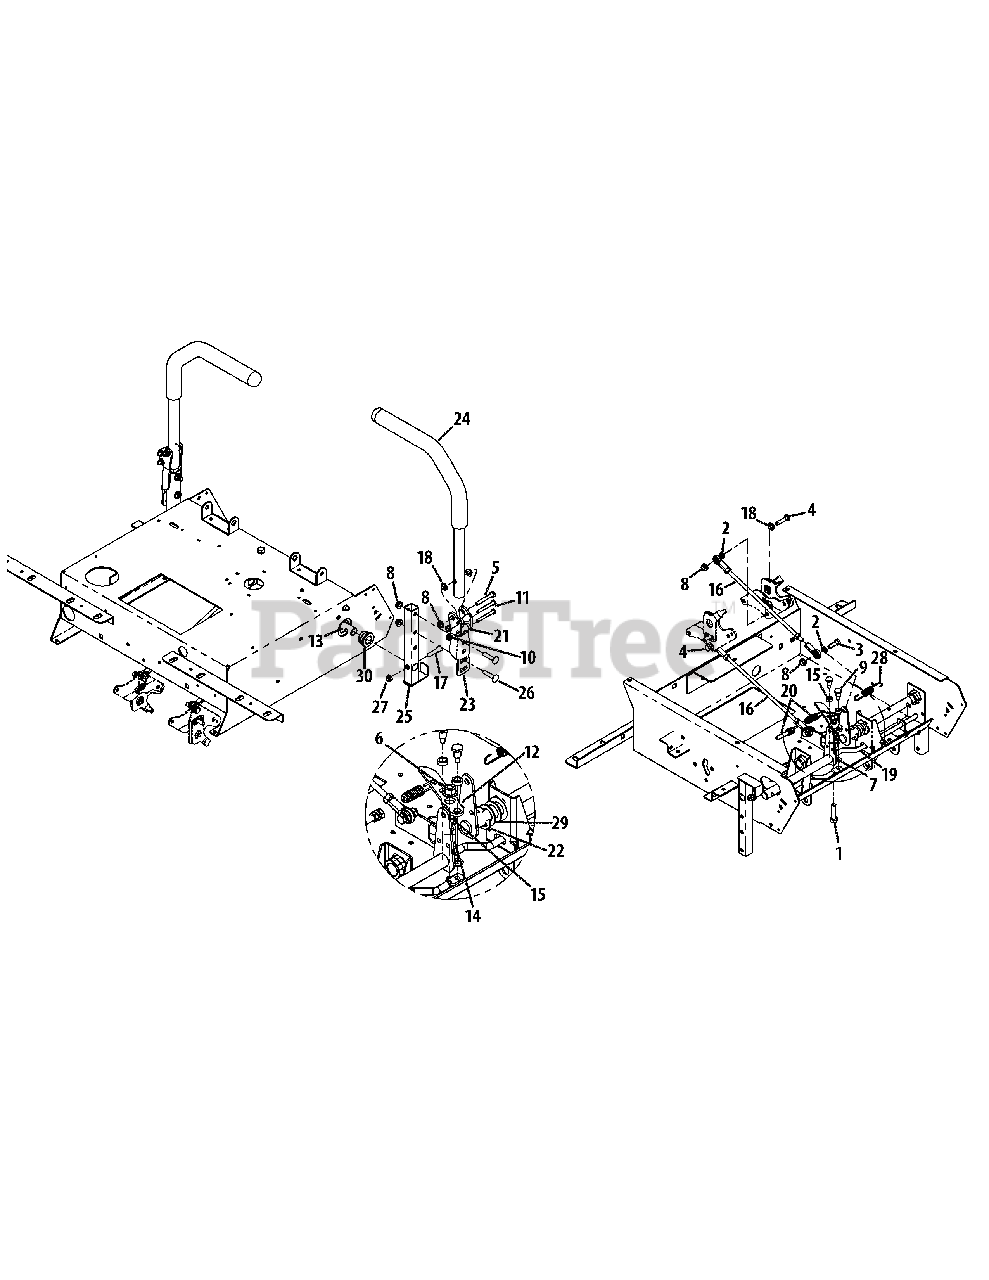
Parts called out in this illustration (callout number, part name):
1	Hex Cap Screw, 3/8-16 x 1-1/2
2	Flat Washer, 5/16
3	Hex Head Cap Screw, 5/16-18 x 1.00
4	Hex Screw, 5/16-18 x 1-1/4
5	Hex Cap Screw, 5/16-18 x 2.00
6	Flange Lock Nut, 3/8-16
7	Flat Washer, 1.4 x .630 x .0515
8	Lock Nut, 5/16-18
9	Shoulder Screw, 1/4-28
10	Hex Flange Lock Nut, 1/4-20
11	Hex Cap Screw, 1/4-20 x 2.00
12	Brake Lever Plate
13	Steering Input Shaft Assembly
14	Spacer, .385 x .625 x .869
15	Spacer, .380 x .563 x .196
16	Steering Link Rod
17	Socket Head Capscrew, 5/16-18 x 1.25
18	Bushing, .310 x .172 x .688 x .06
19	Control Lock Rod
20	Control Cable Lock Out
21	Spacer, .25 x .38 x 1.13
22	E-Clip Retainer Ring
23	Lapbar Pivot Bracket
24	Lapbar Handle/Grip Assembly
25	Pivot Bracket Weldment
26	Carriage Bolt, 5/16-18 x 1.50
27	Nylock Nut, 5/16-18
28	Extension Spring, .544 x 3.35
29	Flat Washer, .793 x 1.24 x .060
30	Hex Flange Bearing, .752
